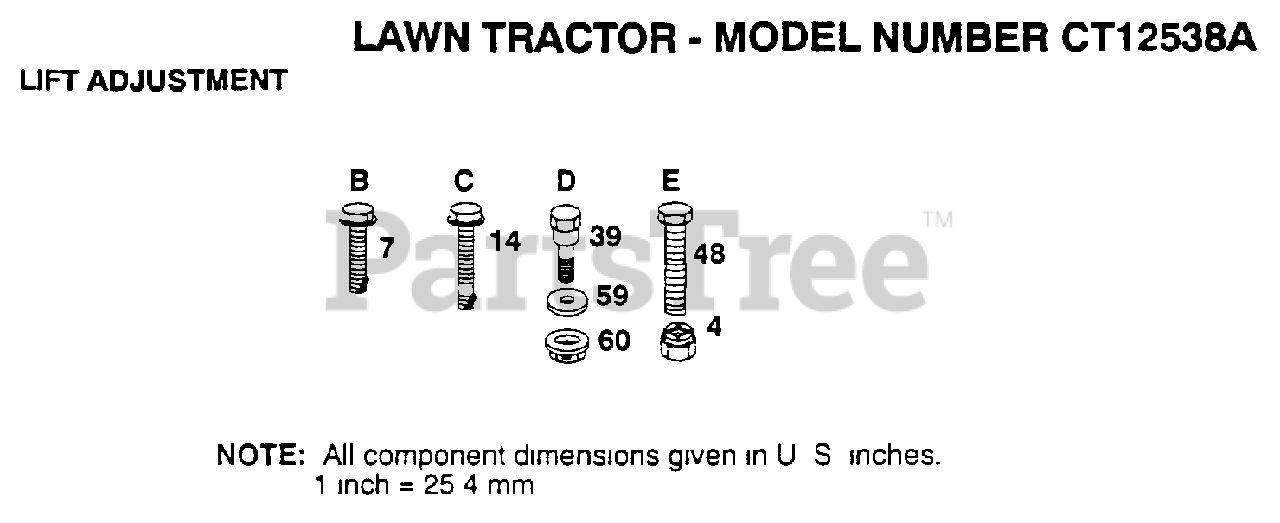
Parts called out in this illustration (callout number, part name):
7	SCREW
14	SCREW
39	"BOLT, SHOULDER LT"
59	WASHER T
60	NUT SPECIAL T
